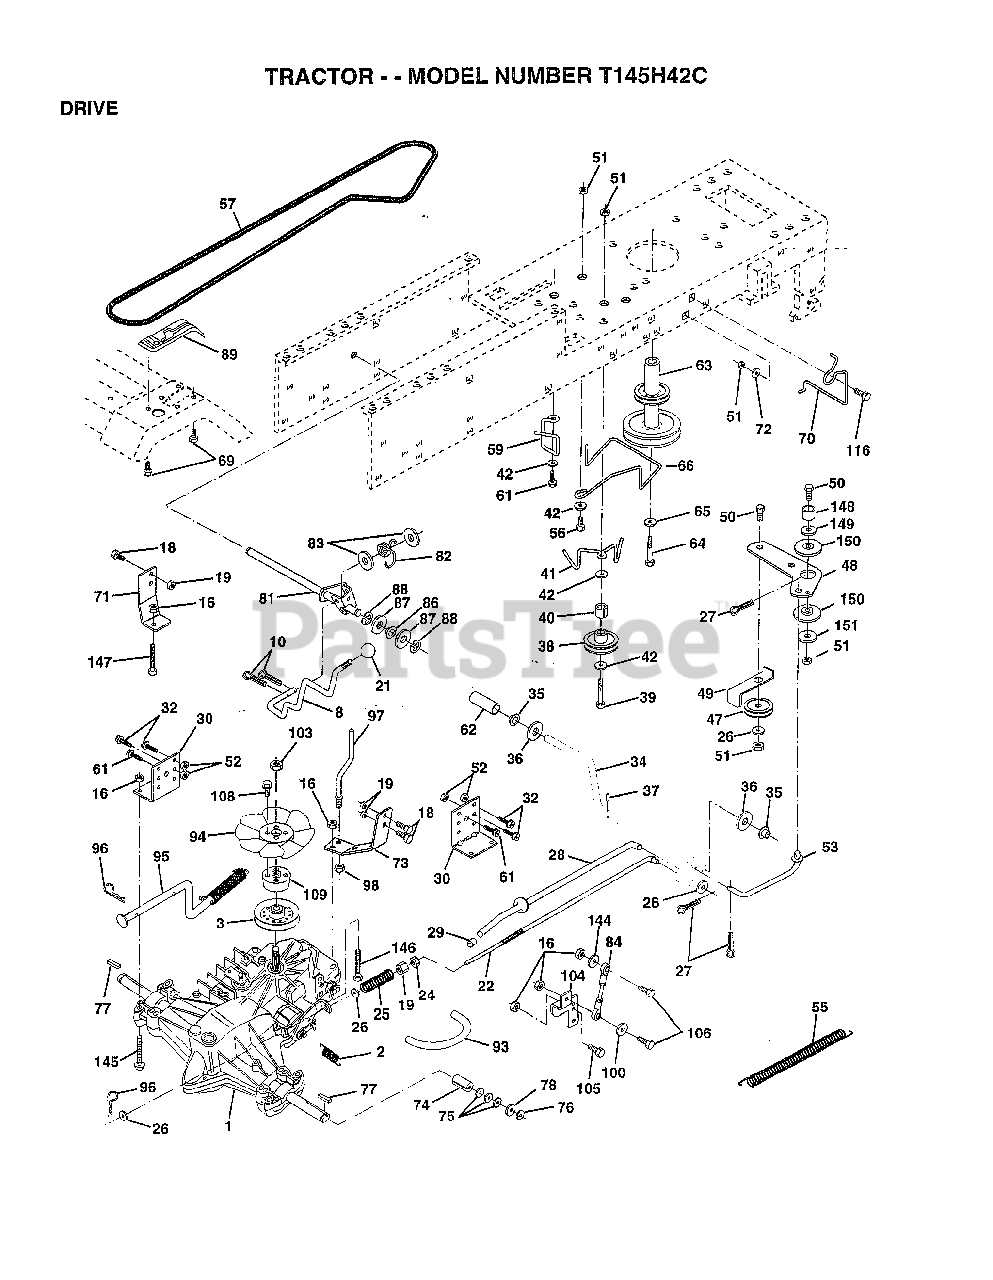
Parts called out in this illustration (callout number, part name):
1	TRANSAXLE HYD 0319-0500
2	SPRING RET BRAKE
3	PULLEY.4.20.HYDRO
8	ROD SHIFT FEND LT
10	PIN COTTER 1/8
16	NUT
18	BOLT
19	NUT
21	KNOB DLX BLK/BLK
22	ROD.BRAKE.HYDRO.
24	NUT
25	SPRING ROD LT
26	WASHER
27	COTTER PIN
28	ROD.BRAKE.PARK.LT
30	TRANSAXLE MTG BKT
32	BOLT
34	SHAFT ASM-PEDAL F
35	NYLON BEARING
36	WASHER LT
38	PULLEY.IDLER.FLAT
39	BOLT
40	SPACER T
42	WASHER
48	BELLCRANK.CLUTCH
49	RETAIN BELT
53	"LINK, CLUTCH T"
55	"SPRING, RETURN LT"
59	KEEPER BELT CNTSP
61	SCREW
62	PEDAL COVER T
63	PULLEY.ENGINE
64	BOLT
65	LOCKWASHER
66	ENGINE BELT KEEPR
69	SCREW HEXWSH H-L
70	KEEPER BELT ENG
71	STRAP.TORQ.LH.HYD
72	WASHER
73	STRAP.TORQ.RH.HYD
74	SPACER SPLIT
75	WASHER
76	E-RING LT
77	SQUARE KEY
78	WASHER
81	SHAFT ASSEMBLY
82	"SPRING,TORSION"
83	WASHER
84	ROD.TIE.BALL.HYD.
86	BUSHING
87	WASHER D
88	KLIP RING
93	"LINE FUEL HYD 4"""
94	"FAN 7"" HYDRO"
97	KEEPER.BELT.RH.HY
98	NUT
100	WASHER M
104	ARM.CONTROL.PUMP
105	SCREW CAP 5/16-18
106	BOLT
108	SCREW.HXHD.10-20
109	ADAPTOR.FAN.HYDRO
116	BOLT RDHD 3/8-16
144	WASHER
145	BOLT.HEX.FLGHD
146	BOLT.HEX.FLGHD
147	BOLT.HEX.FLGHD.
149	SPACER RETAINER
150	BUSHING.NYLON
151	WASHER
